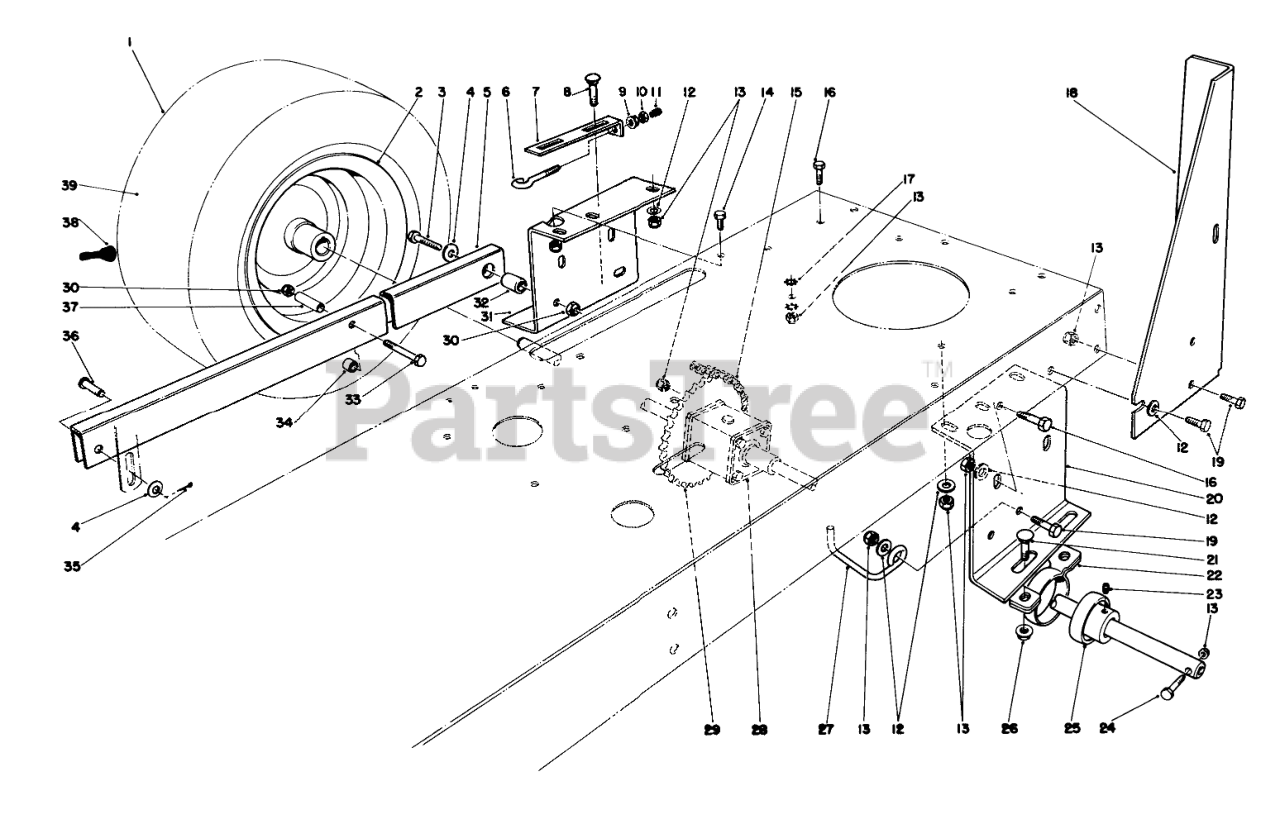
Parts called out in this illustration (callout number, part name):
3	SCREW-HH
4	WASHER-FLAT
5	REAR SUSP ARMR
6	SCREW-ADJUSTING
7	PLATE-ADJUSTING
8	BOLT-CARR
9	NUT-HF
10	NUT-HEX
11	VINYL ROD TIP
12	WASHER-PLAIN
13	NUT-LOCK, NI
14	SCREW-HH
15	ROLLER CHAIN
16	SCREW-HH
17	WASHER-LOCK, INTERNAL
18	LH STANDBAR B
19	SCREW-HH
20	LH REAR AXLE SUPT R
21	SCREW-CARR
22	RTNR-PILLOW BLK
23	SCREW-SET, HSH
24	SCREW-HH
25	Bearing-Ball (Incl. Ref. #23)
26	NUT-HF
27	BELT GUIDE
28	DIFFERENTIAL
29	42T DIFF SPROCKET
30	NUT-LOCK, CONE
31	RH REAR AXLE SUPT R
32	PIN-SUPT ARM
33	SCREW-HH
34	INNER TUBE SPACER
35	PIN-COTTER
36	PIN-CLEVIS
37	OUTER TUBE SPACER
38	STEM-VALVE
39	TUBE-INNER
